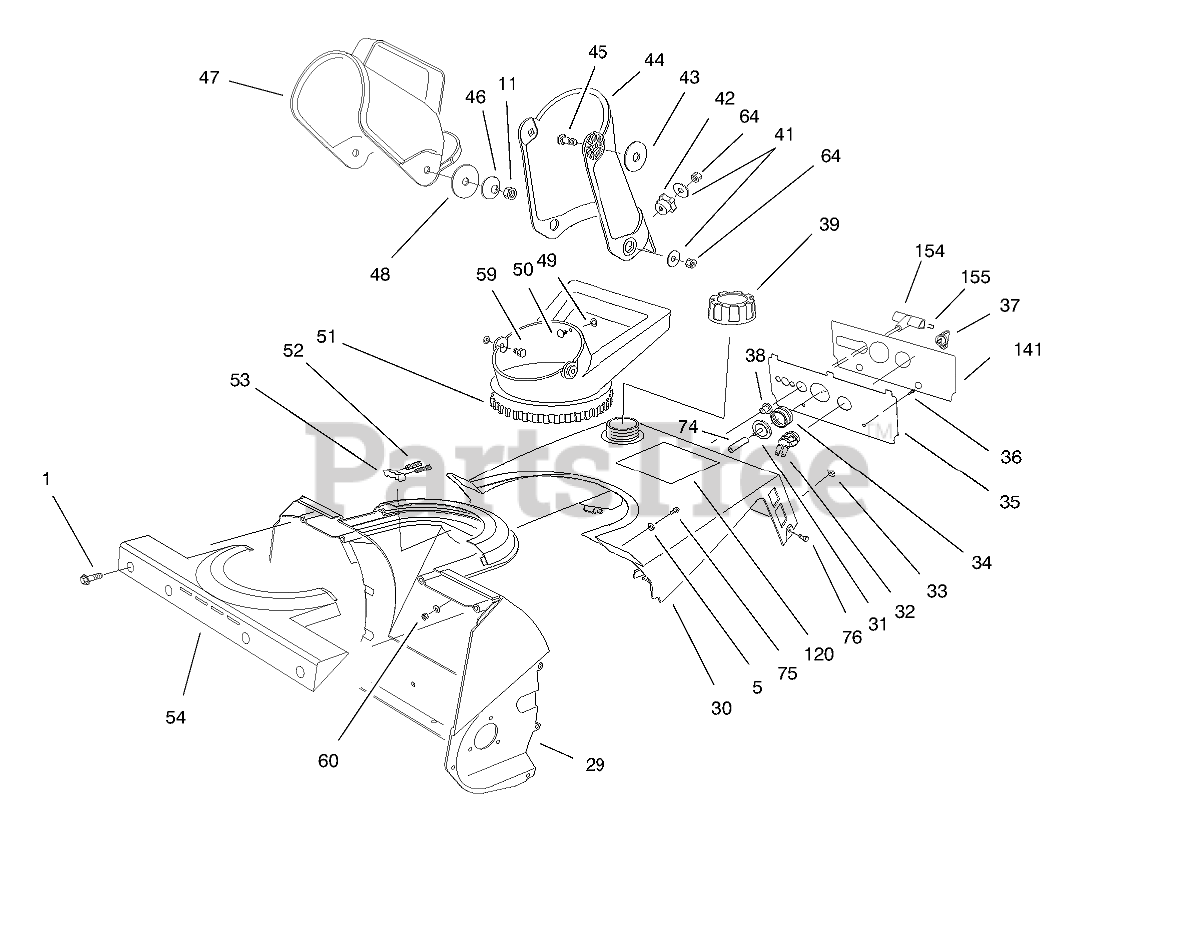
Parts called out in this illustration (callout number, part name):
1	SCREW-PLASTIC
5	WASHER-FLAT
11	NUT-LOCK, NI
29	HOUSING
30	Shroud-Upper
31	BODY-PRIMER
32	SWITCH
34	BULB-PRIMER
36	SCREW-SHWH, THREAD FORMING
37	KEY-IGNITION
38	GUIDE-ROPE, STARTER
39	CAP-FUEL ASM
41	WASHER-FLAT
42	KNOB-CHUTE
43	WASHER-RUBBER
44	Chute
45	BOLT-CARR
46	WASHER-BELLEVILLE
47	DEFLECTOR-CHUTE
48	WASHER-FLAT
49	PUSHNUT-RETAINER, BOLT
50	SCREW-CARR
51	HANDLE-CHUTE
52	SPRING-COMPRESSION
53	DETENT-CHUTE
54	RETAINER-CHUTE
59	SCREW-HH
60	NUT-LOCK, NI
64	NUT-LOCK, NI
74	HOSE-PRIMER
75	SCREW-PPH
76	SCREW-THREAD FORMING
78	Panel-Control
120	DECAL - POWERLITE EL.
141	DECAL
154	HANDLE-STARTER
155	STAPLE-HANDLE
